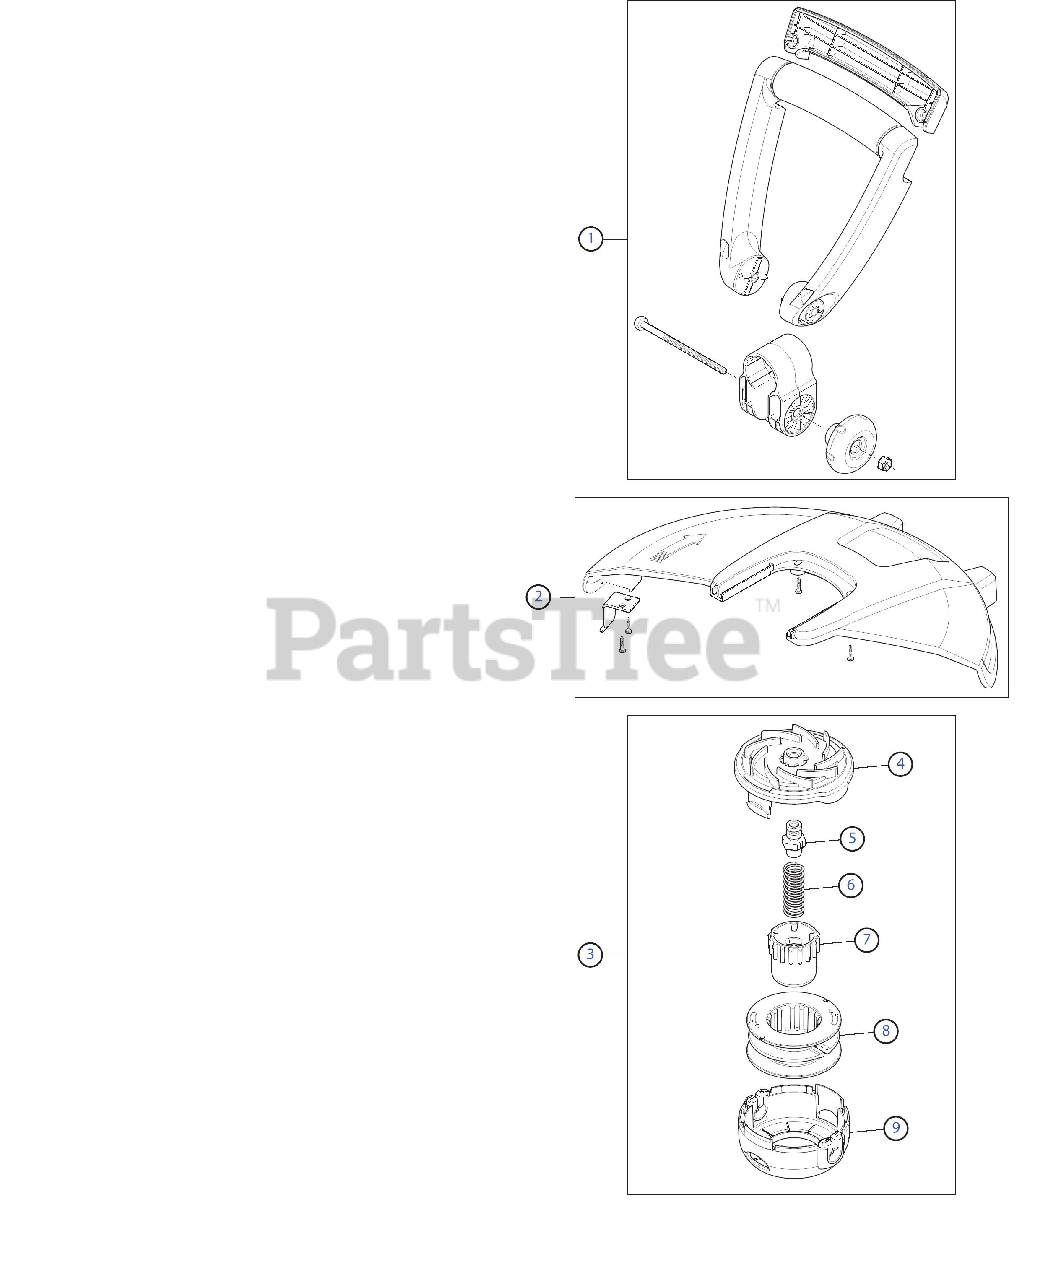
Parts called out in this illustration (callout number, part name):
1	Handle Assembly
2	Shield and Blade Assembly
3	Cutting Head Assembly
7	Bump Knob
9	Spool Cover
